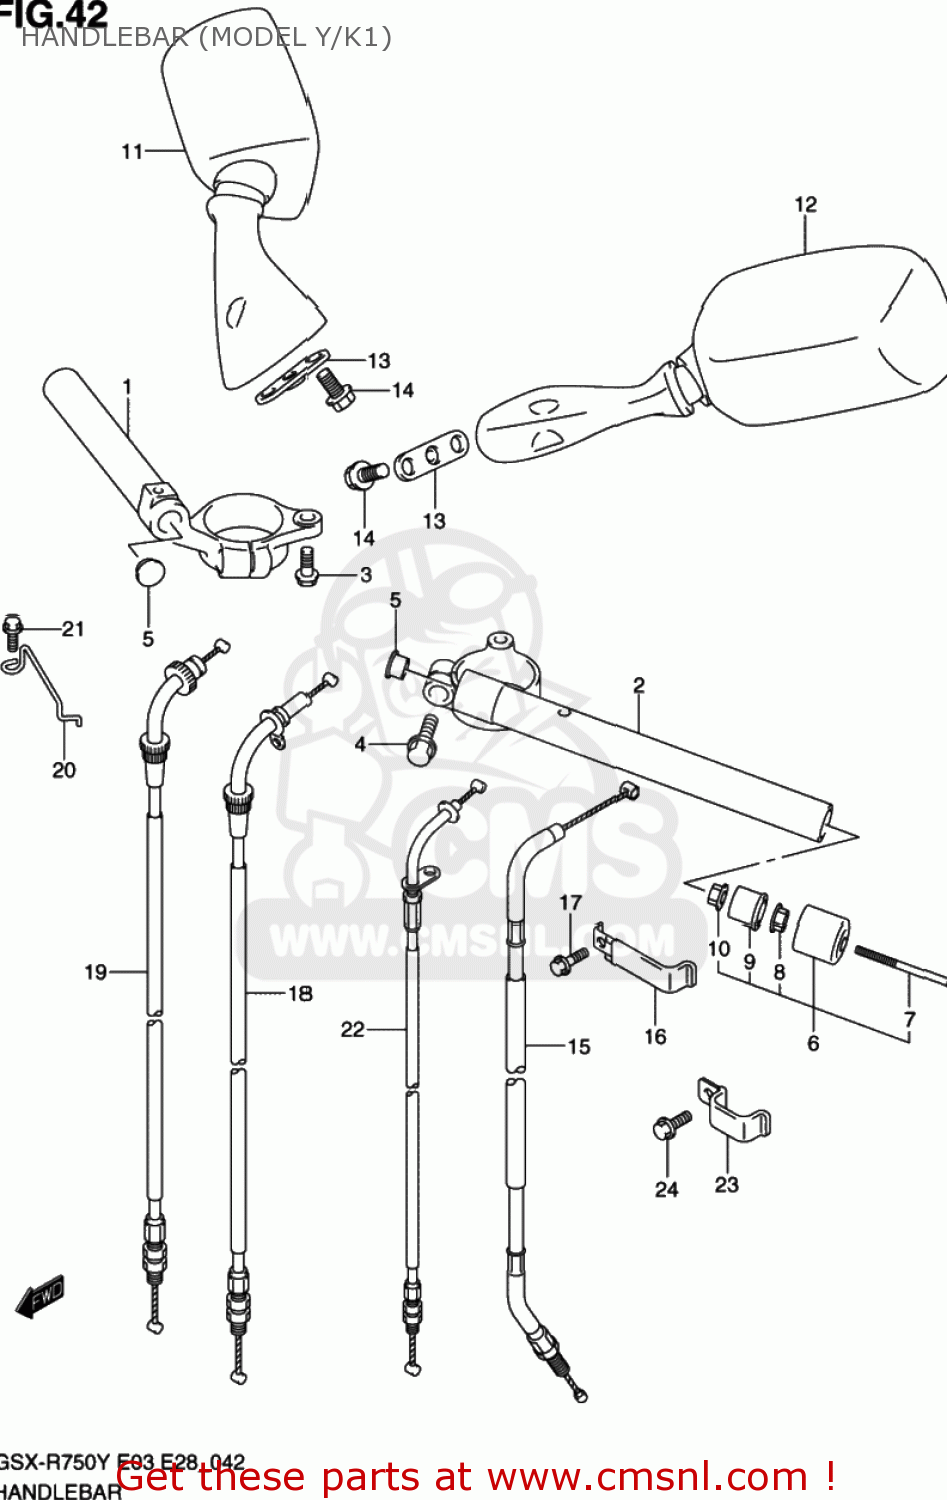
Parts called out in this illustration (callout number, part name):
1	HANDLEBAR,R
2	HANDLEBAR,L
3	BOLT
4	BOLT,HANDLEBAR
5	PLUG(OD:17)
6	BALANCER,HANDLEBAR
7	SCREW
8	NUT
9	EXPANDER,HANDLE BALANCER
10	NUT
11	MIRROR ASSY,RR VIEW,R
12	MIRROR ASSEMBLY,REAR VIEW
13	CUSHION,RR VIEW MIRRORR
14	BOLT,G/S SWITC
15	CABLE ASSY,CLUTCH
16	CLAMP,WIRING HARNESS
17	BOLT
18	CABLE ASSY,THROTTLE NO.1
19	CABLE ASSY,THROTTLE NO.2
20	GUIDE, CABLE
21	BOLT
22	CABLE,STARTER
23	CLAMP
24	BOLT
